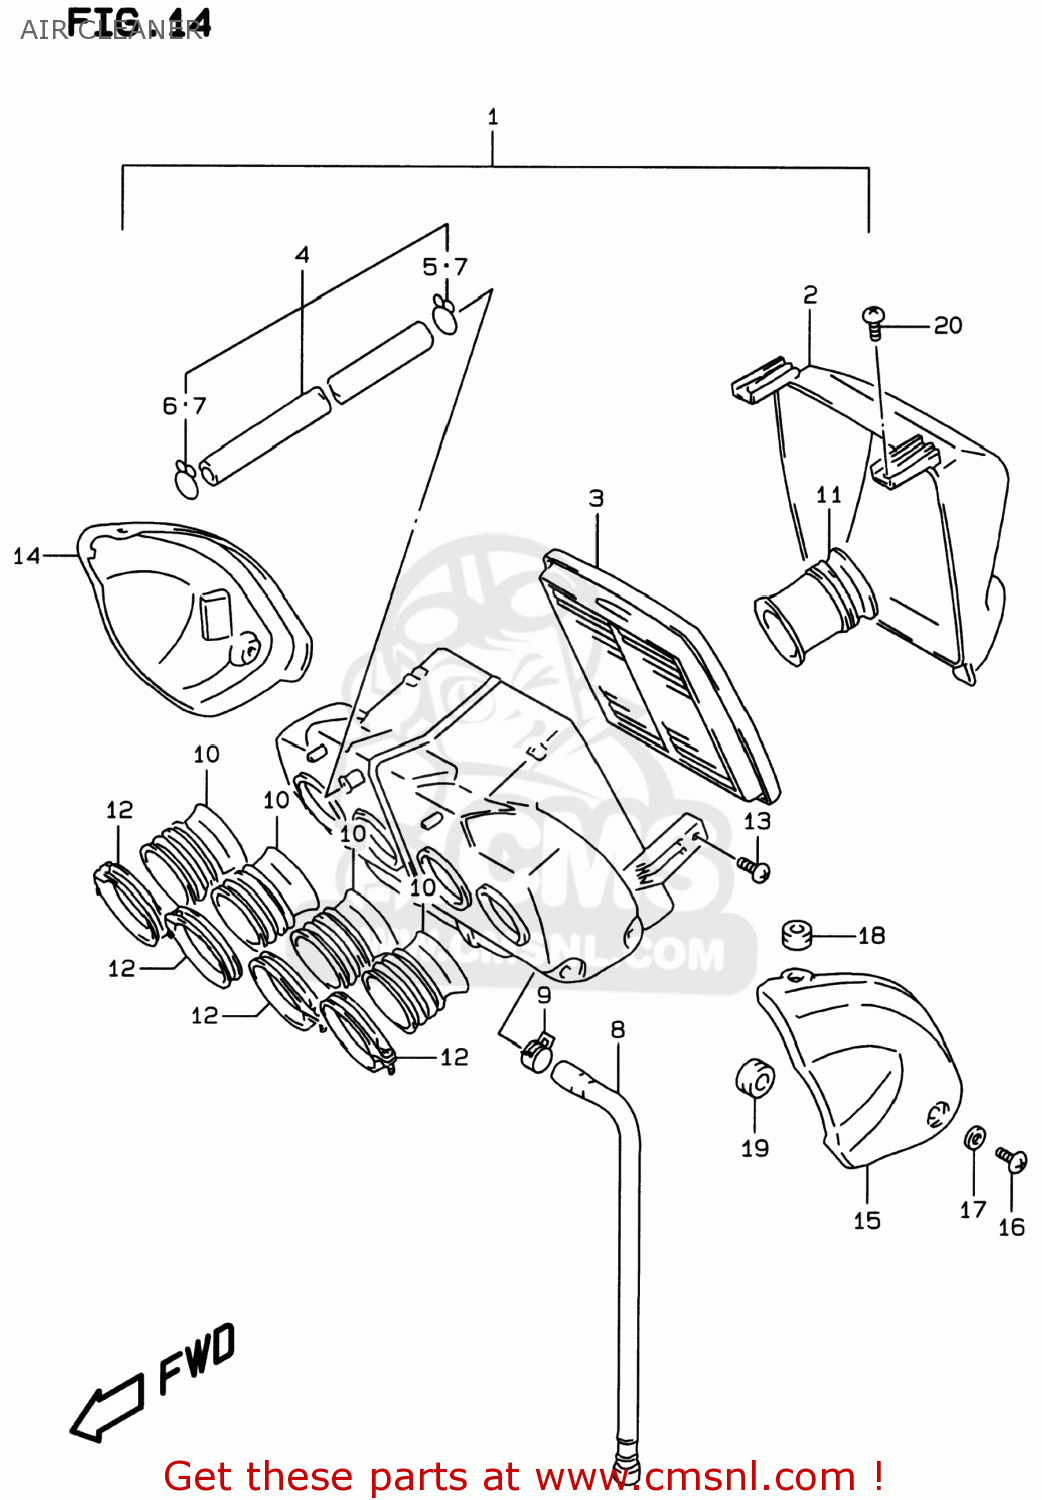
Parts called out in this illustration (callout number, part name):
1	CLEANER ASSY,AIR
2	CAP,AIR CLEANER
3	FILTER,AIR
4	TUBE,BREATHER
5	CLIP
6	CLIP
7	CLIP
8	TUBE,DRAIN
9	CLIP
10	TUBE,OUTLET
11	TUBE,INLET
12	CLAMP
13	SCREW
14	COVER,AIR CLEANER,RIGHT
15	COVER,AIR CLEANER,LEFT
16	SCREW(5X14)
17	WASHER
18	CUSHION
19	CUSHION
20	SCREW 6X12
